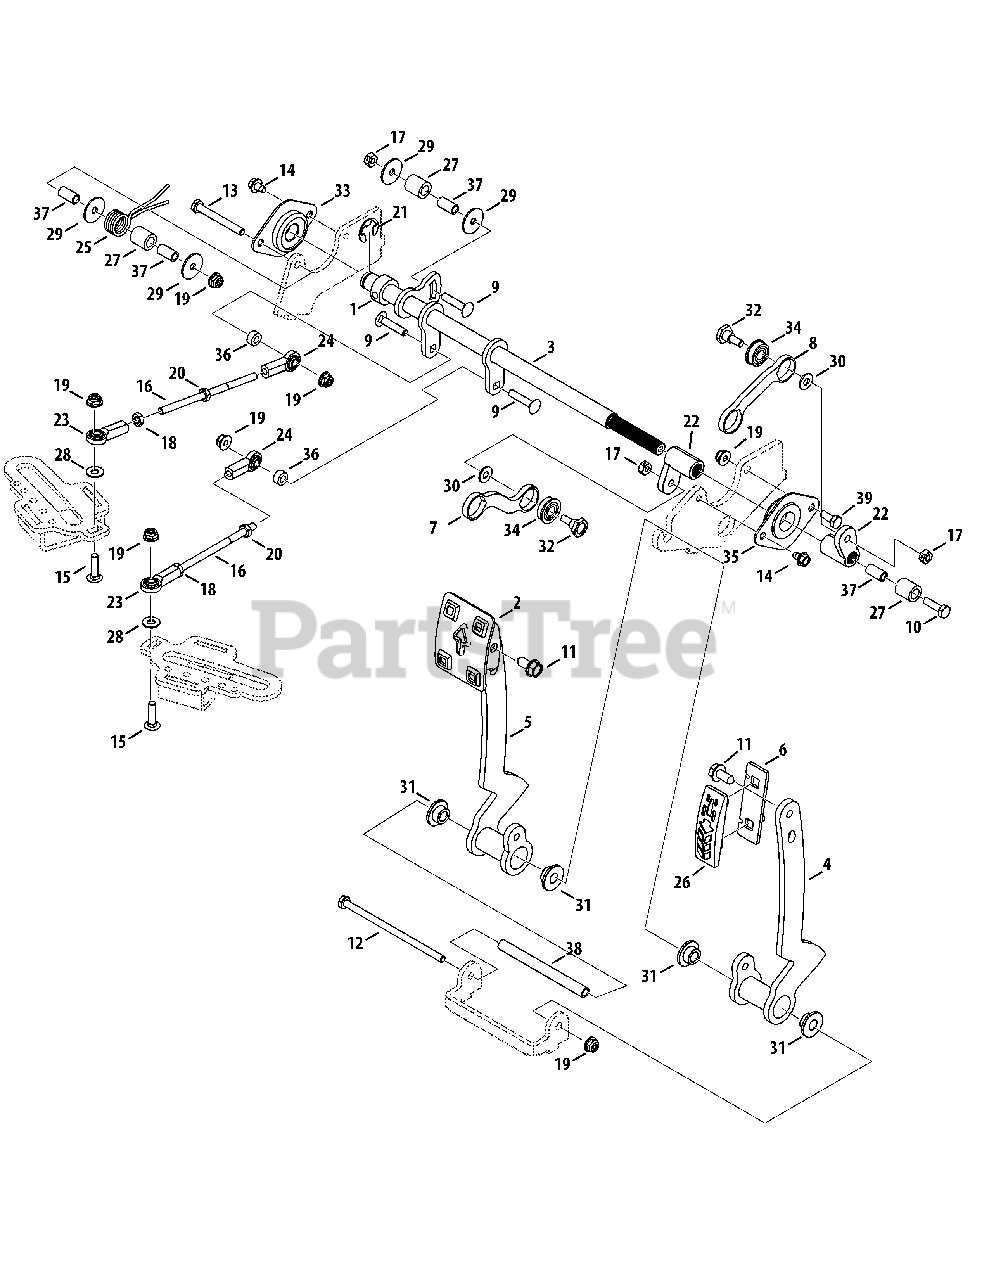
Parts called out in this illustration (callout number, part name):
1	Shaft Collar, .625 x 1.0 x .438
2	Forward Pedal Assembly
3	Speed Control Arm Assembly
4	Reverse Pedal Assembly
5	Forward Pedal Assembly
6	Reverse Pedal Bracket
7	Forward Pedal Link
8	Reverse Pedal Link
9	Carriage Screw, 1/4-20 x 1.25
10	Hex Cap Screw, 1/4-20 x 1.25
11	Screw, 5/16-18 x .750
12	Hex Cap Screw, 1/4-20 x 5.00
13	Hex Cap Screw, 1/4-20 x 2.25
14	Screw, 1/4-20 x .375
15	Carriage Screw, 1/4-20 x 1.00
16	Speed Control Link Rod
17	Nut, 1/4-20, Hexlock
18	Jam Nut, 1/4-28
19	Nut, 1/4-20, Flangelock
20	Jam Nut, 1/4-28, LH
21	E-Ring, .625
22	Pedal Shaft Arm
23	Rod End, 1/4-28
24	Rod End, 1/4-28, LH
25	Torsion Spring, .70 ID
27	Spacer, .385 x .625 x .700
28	Washer, .250 x .630 x .052
29	Washer, .255 x 1.00 x .060
30	Washer, .271 x .630 x .065
31	Shoulder Spacer, .38 x .62 x 1.00
32	Shoulder Screw, .375 x .280, 1/4-20
33	Ball Bearing, .625
34	Bearing, .375 x .875 x .281
35	Ball Bearing, .750
36	Spacer, .256 x .500 x .240
37	Spacer, .260 x .375 x .75
38	Spacer, .255 x .375 x 4.28
39	Hex Cap Screw, 1/4-20 x .75
